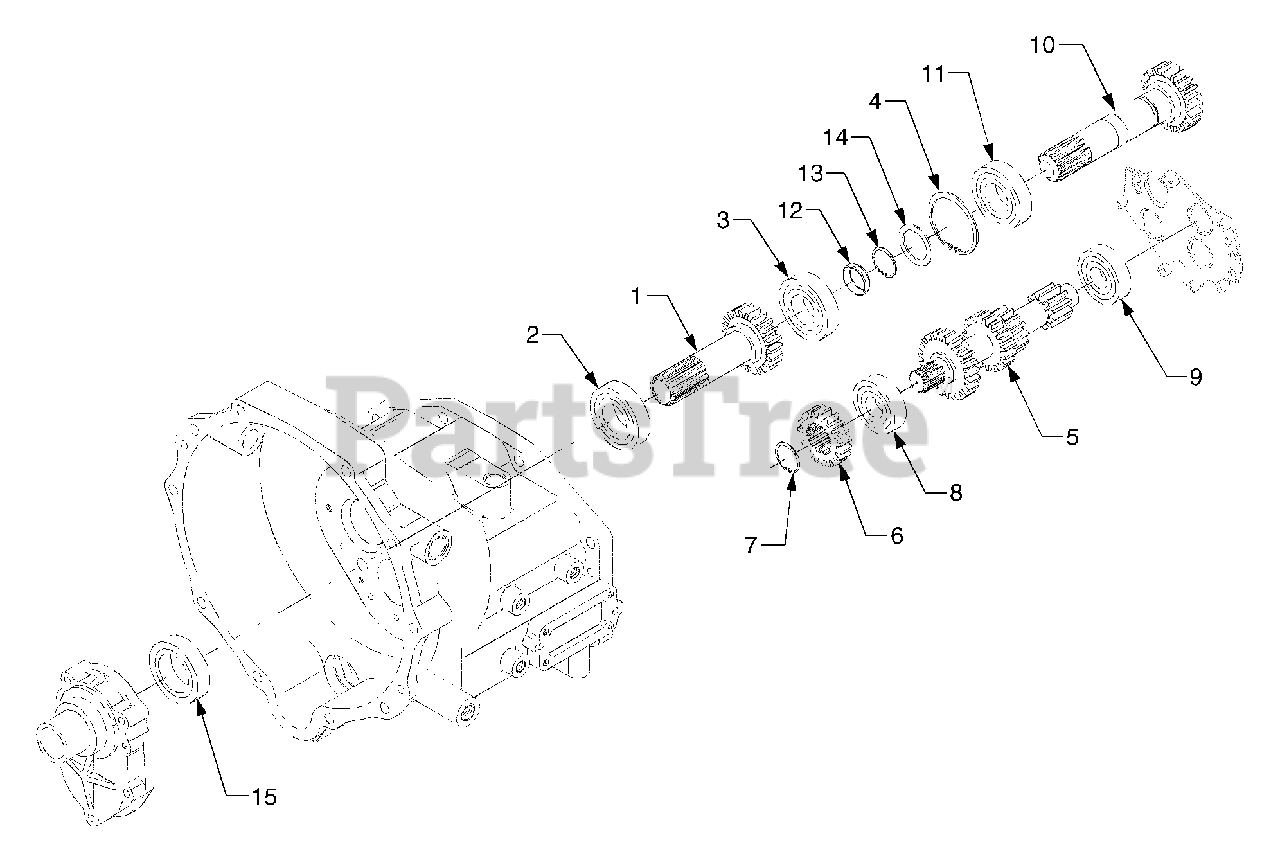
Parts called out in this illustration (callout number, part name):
1	Shaft, 25 Gear
2	Bearing, Ball
3	Bearing, Ball
5	Gear, Main Shaft
8	Bearing, Ball
9	Bearing, Ball
10	Shaft, 22 Gear (PTO)
11	Bearing, Ball
